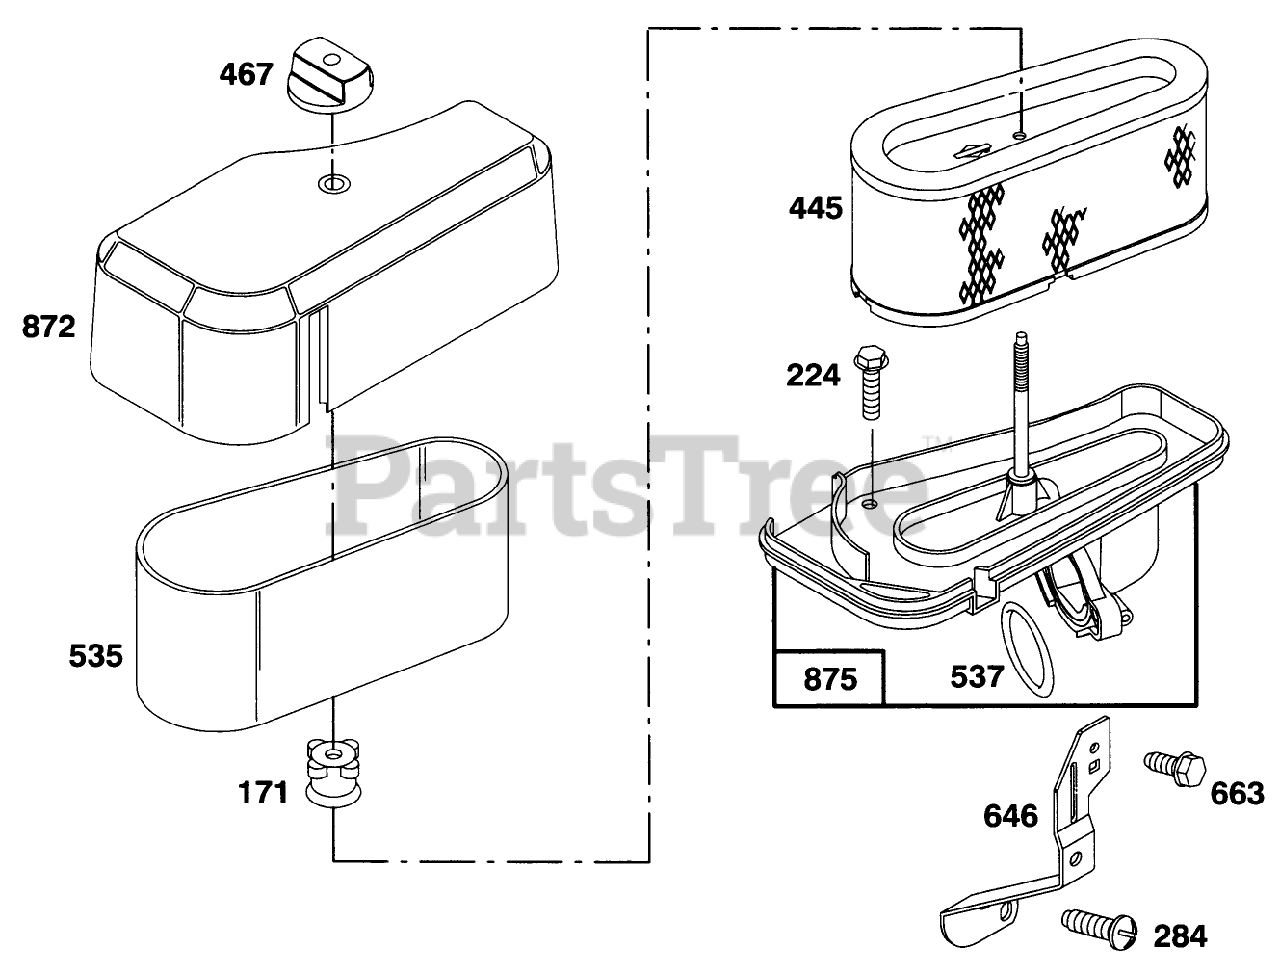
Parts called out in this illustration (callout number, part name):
224	Screw-Sem
284	Screw-Pan Head
445	Filter-Air
535	Filter-Air
537	O-Ring
646	Brace-Air Cleaner
663	Screw
872	Cover-Air Cleaner
875	Base-Air Cleaner
